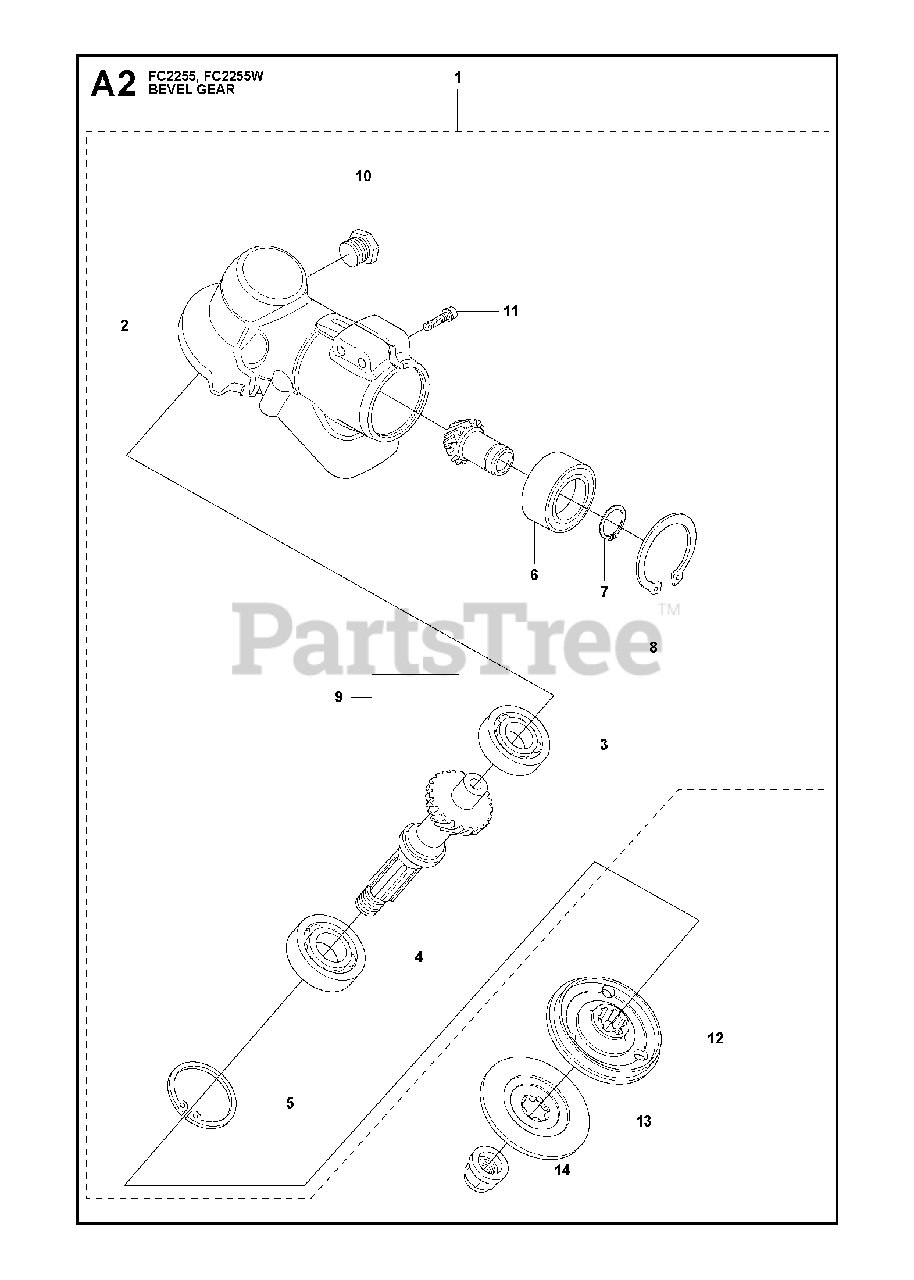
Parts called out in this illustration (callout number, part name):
1	BEVEL GEAR
2	%GEAR HOUSING
3	BALL BEARING
5	RETAINING RING SGH 35
6	BEARING
7	RETAINING RING SGA 15
8	RETAINING RING
9	BEVEL GEAR
10	PLUG
11	SCREW
13	SUPPORT FLANGE
14	BLADE NUT
